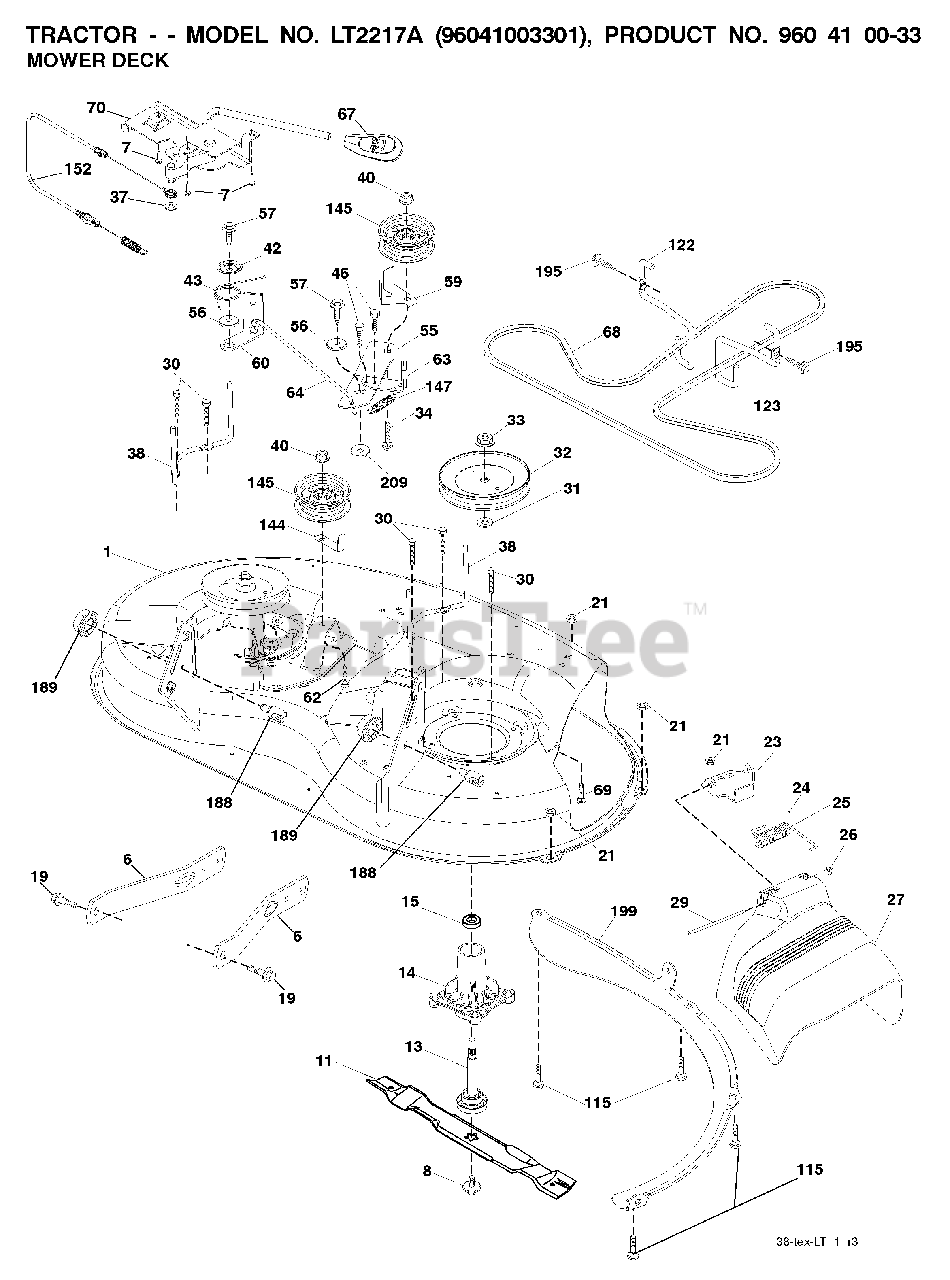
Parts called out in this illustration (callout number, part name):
6	ARM.SUSPENSION.MOWER.R
7	SCREW
8	BOLT.WASHER.ASM.7/16-2
11	BLADE 38" PREMIUM
13	SHAFT.ASM.MDRL.N/GREASE.38
14	HOUSING MANDREL
19	BOLT.SHOULDER
21	LOCKNUT
23	BRKT.DEFLECTOR.38"2005+
24	CAP-SLEEVE LT
25	SPRING.TORSION.DEFLECT
26	NUT PUSH M
29	ROD.HINGE
30	SCREW, WASHER HEAD
31	WASHER.SPACER.MANDREL
32	PULLEY.MANDREL.5.0.PD.38"
33	NUT.FLANGE.LOCK.TOP
38	KEEPER BELT LH MANDREL
40	NUT LOCK FLG 3/8-16 UNC
42	SPRING.TORSION.BRAKE
43	SRPING.TORSION.RETAINE
46	SCREW.1/4-20X5/8
55	IDLER.ARM
56	SPACER.RETAINER
57	SCREW 3/8-16X1
59	GUARD, BELT
60	ARM BRAKE MOWER RH 38"
62	BOLT.3/8-16X1.50
63	ARM BRAKE MOWER RH
64	LINK BRAKE
67	HANDLE.CLUTCH.CABLE.LT
69	BOLT
70	CLUTCH.ASM.MANUAL.LT.TEX
115	BOLT
122	KEEPER BELT ENGINE LH
123	KEEPER BELT RH
144	KEEPER BELT
145	PULLEY.IDLER.48"PRIMARY
147	SPRING RETURN
152	CLUTCH CABLE
188	STUD.FASTNER.W/ANTI-ROTATE
189	NUT LOCK HEX FLANGE 5/16-18
195	SCREW, 3/8-16X3/4
199	BAFFLE VORTEX
205	SCREW
208	SCREW 3/8-16X1/2
209	WASHER 12/32X2X10GA
